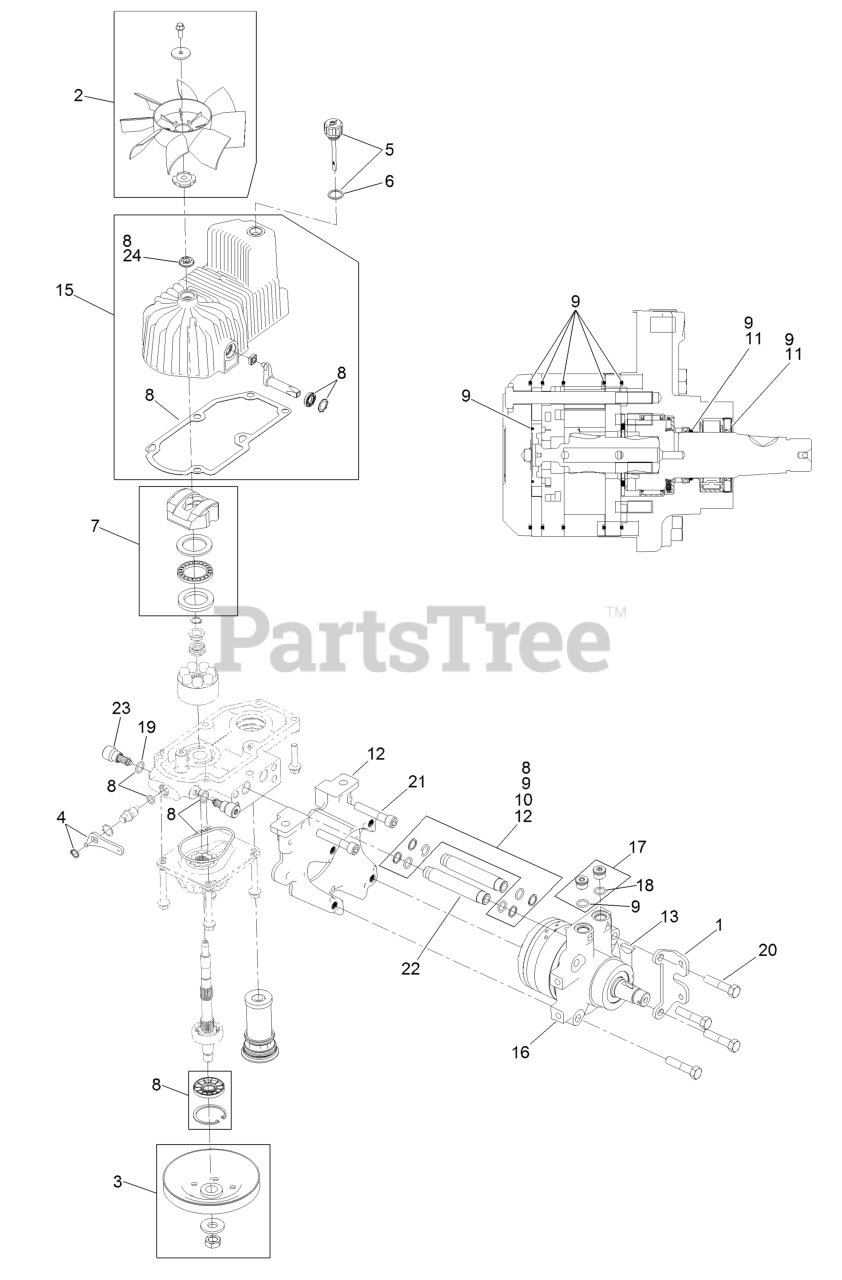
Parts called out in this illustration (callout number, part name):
1	Mount-Shoe, Horse
2	Fan Kit
3	Pulley Kit
4	Handle-Bypass Valve, Hydro
5	Dipstick-Hydro W/Gasket
6	Gasket-Dipstick, Hydro
7	Swash Block Kit
8	Pump Seal Kit
9	Motor Seal Kit
10	Tube Seal Kit
11	Output Shaft Seal Kit
12	Nose Cup-Uht
13	Key-Woodruff
15	Housing-RH
16	Motor-Hydraulic RH 240Cc
17	Magnetic Plugs Service Kit
19	O-Ring-Check Valve
20	Screw HH
21	Screw-HSH
22	Hydraulic Tube Kit
23	Shock Valve, 12Cc Hydro
24	Seal-Fan Drive
99	Puller-Pulley
99	Flow Test Kit
